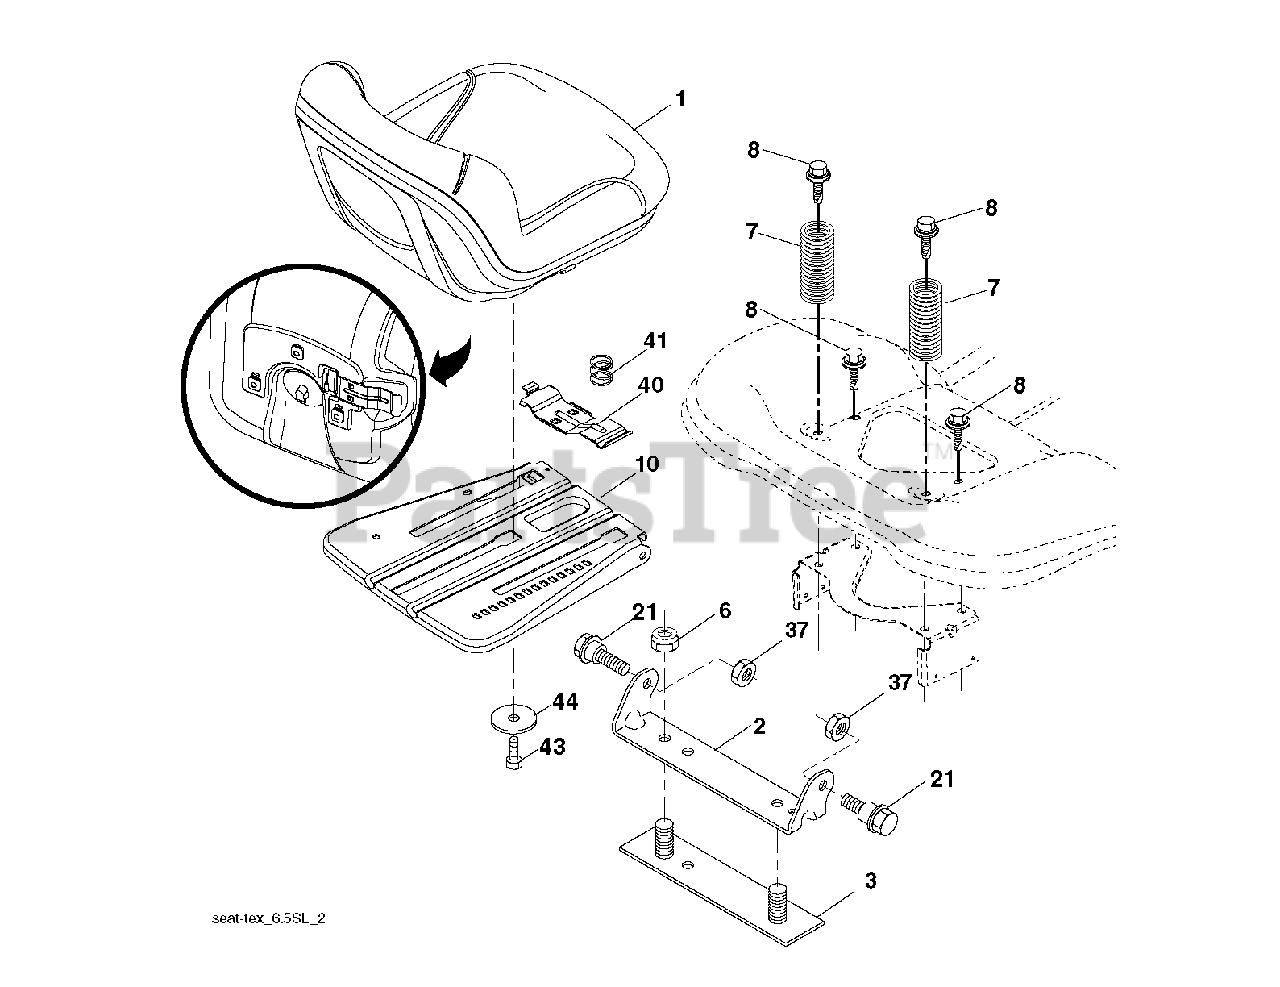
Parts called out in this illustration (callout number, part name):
1	SEAT.TH150.MS498.GRY.HUSQ.TEX
2	BRKT.PIVOT.FENDER
3	STRAP
6	NUT
7	SPRING COMPRESSION
8	BOLT, 5/16-18 X 1 3/4
10	PAN.ASM.SEAT.3PT
21	BOLT.SHOULDER.5/16-18
37	NUT.71038.31-18.HEX.NYLOCK
40	HANDLE.SLIDE.SEAT.TEX.BLACK
41	SPRING.LATCH.SEAT.TEX
44	WASHER 13/32 X 2-3/8 X 12GA
